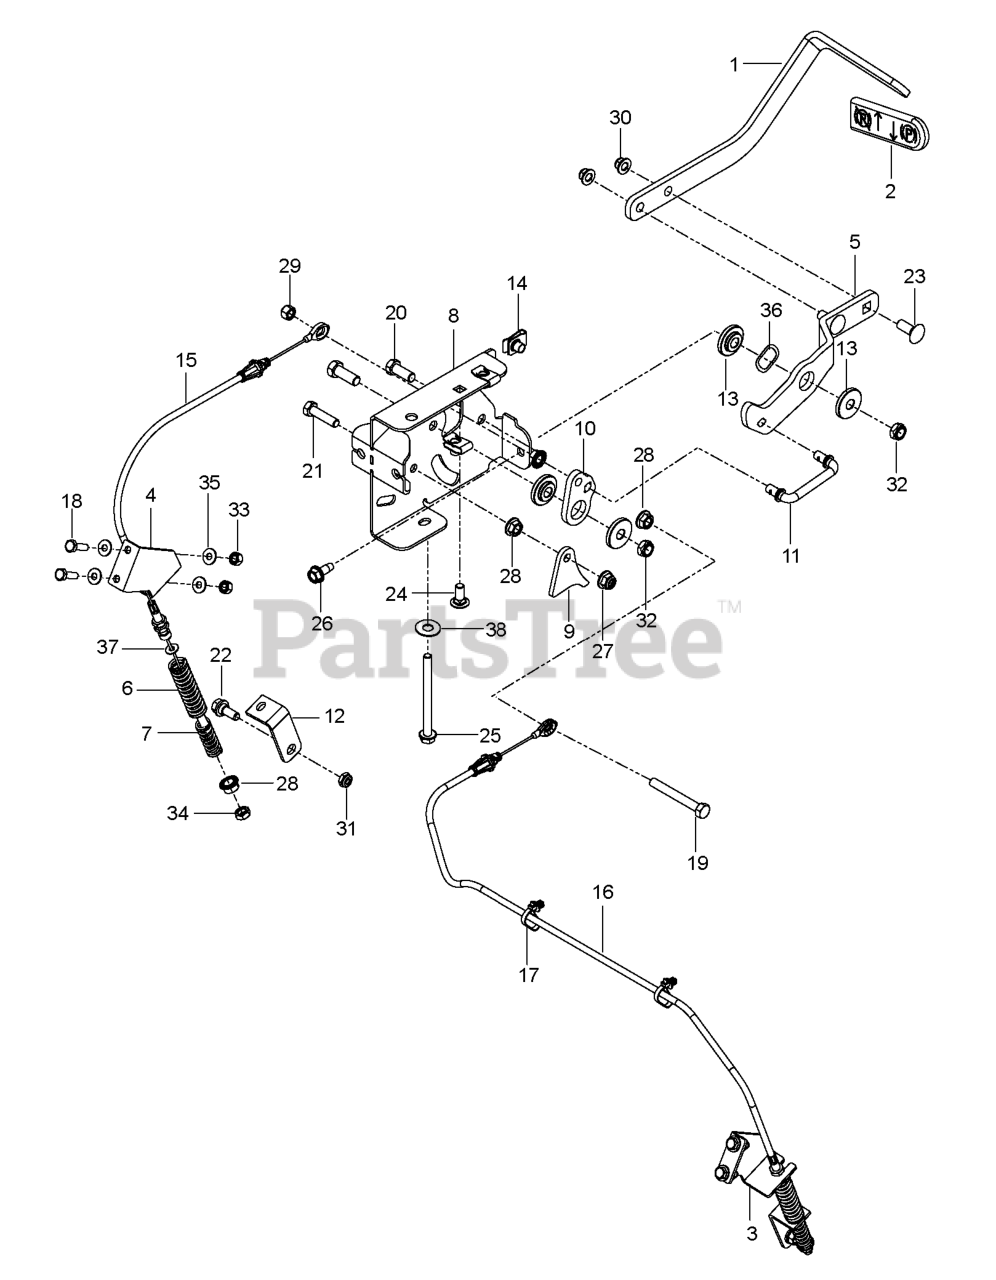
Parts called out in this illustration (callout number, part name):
1	ARM, BRAKE
2	GRIP, PARK BRAKE
3	BRKT, BRAKE RT, BLK
4	BRKT, BRAKE LT, BLK
5	LEVER.PNT.BRAKE.E-DIP
6	SPRING, RETURN
7	SPRING, ENGAGEMENT
8	MOUNT, BRAKE WLDMT
9	ACTUATOR, SWITCH
10	BELLCRANK, BRAKE
11	LINKAGE, BRAKE
12	BRKT, BRAKE, BLK
13	BUSHING, BRAKE
14	U-CLIP 5/16-18 NUT RETAINER
15	CABLE.ASSY.BRAKE.CABLE.SHORT
16	CABLE.ASSY.BRAKE.CABLE.LONG
17	TIE WRAP, 8-3/8", W/CLIP
18	HCS 1/4-20X7/8 GR5
19	HCS 5/16-18 X 2 1/2 TPBLT
20	HCS 3/8-16X1.GRD.5.ZD
21	HCS 5/16C X 1
22	BOLT, SHOULDER
23	RHSNB 3/8C X 1
24	BOLT 5/16C X 3/4" CARRIAGE
25	HHFS 5/16-18 X 3 3/4
26	BOLT 5/16-18 X 3/4
27	5/16-18 NYLOC FLANGE NUT
28	NUT 5/16C WHIZ
29	NUT 5/16 NYLOC
30	NUT 3/8-16 HEX FLG NYLOC ZD
31	NUT.71038.31-18.HEX.NYLOCK
32	NUT HEX 3/8-16 NYLON, THIN
33	NUT.1/4-20.HEX.NYLOC.ZD
34	NUT 5/16-18 HEX JAM ZD
35	WASHER 1/4 SAE
36	WASHER, .825 X 1.087, WAVE
37	WASHER 3/8 SAE FLAT
38	WASHER.9/16 X 1 3/8 X 12 GA.
